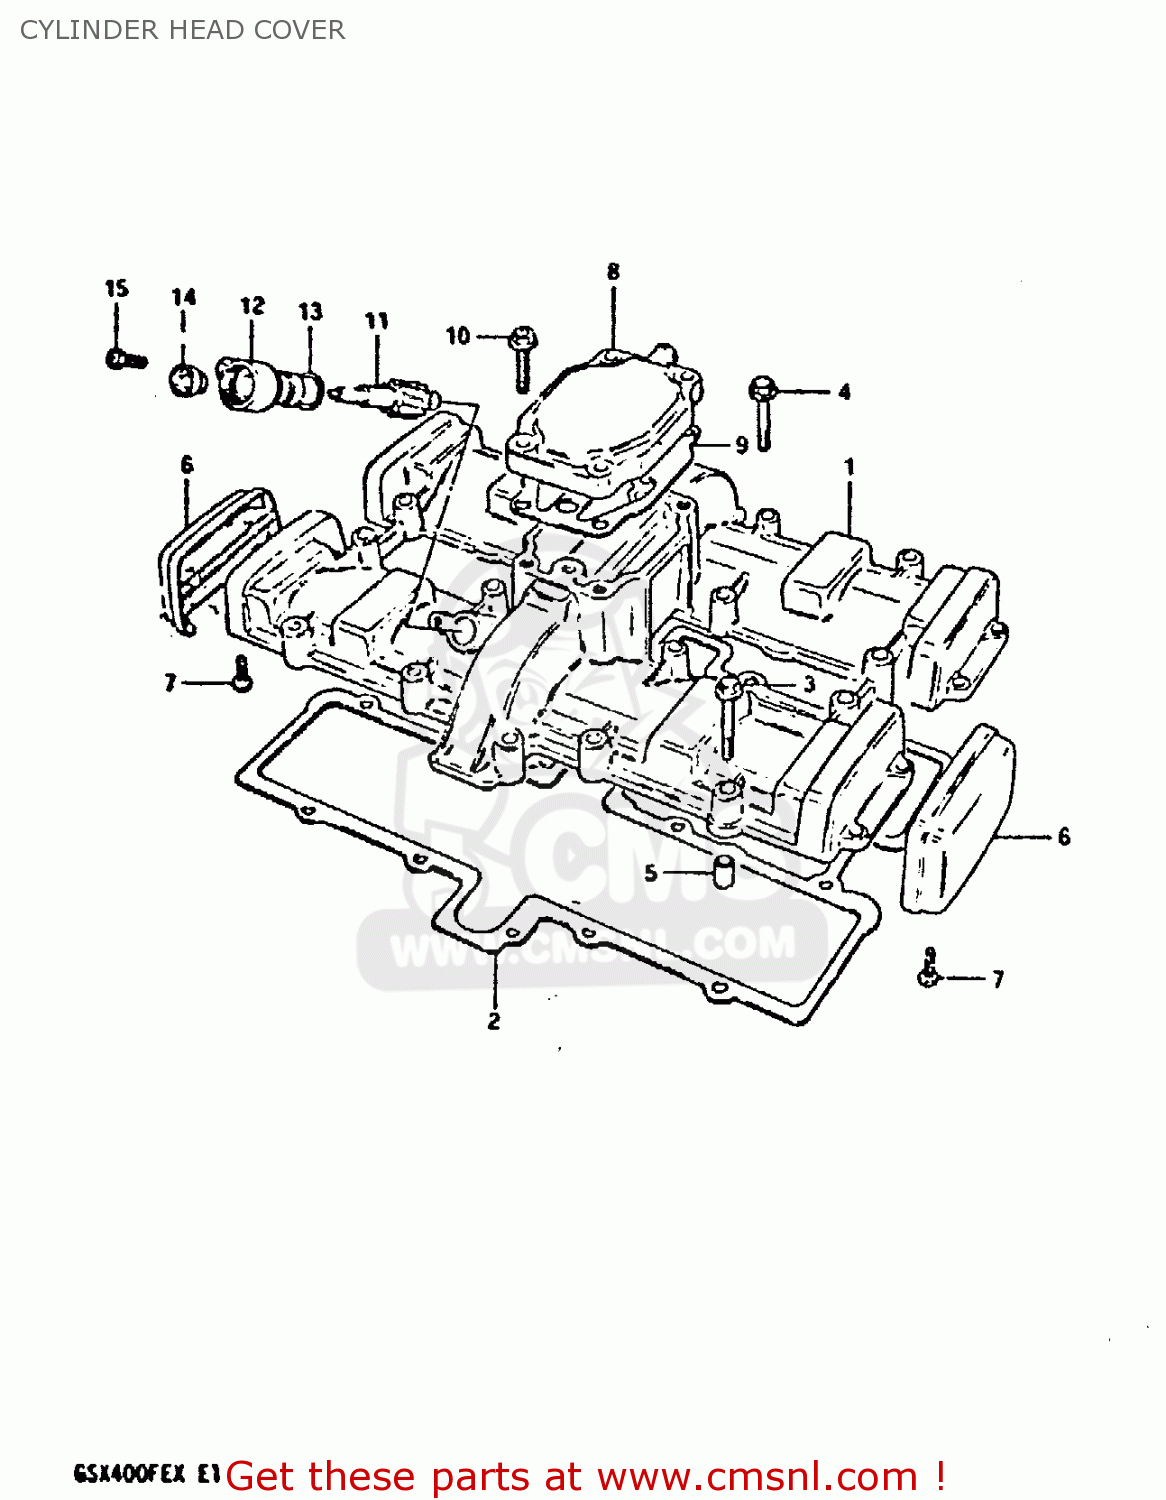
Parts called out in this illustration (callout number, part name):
1	COVER, CYLINDER HEAD
2	GASKET (MCA)
3	BOLT
4	BOLT 6X35
5	PIN(6.2X8X11)
6	CAP, CYLINDER HEAD COVER
7	SCREW
8	COVER, BREATHER
9	GASKET (MCA)
10	BOLT
11	GEAR,TACHOMETER DRIVEN
12	SLEEVE,TACHOMETER DRIVE GEAR
13	SEAL,TACHOMETER DRIVEN
14	SEAL,OIL(5X12X8)
15	SCREW(5X12)
